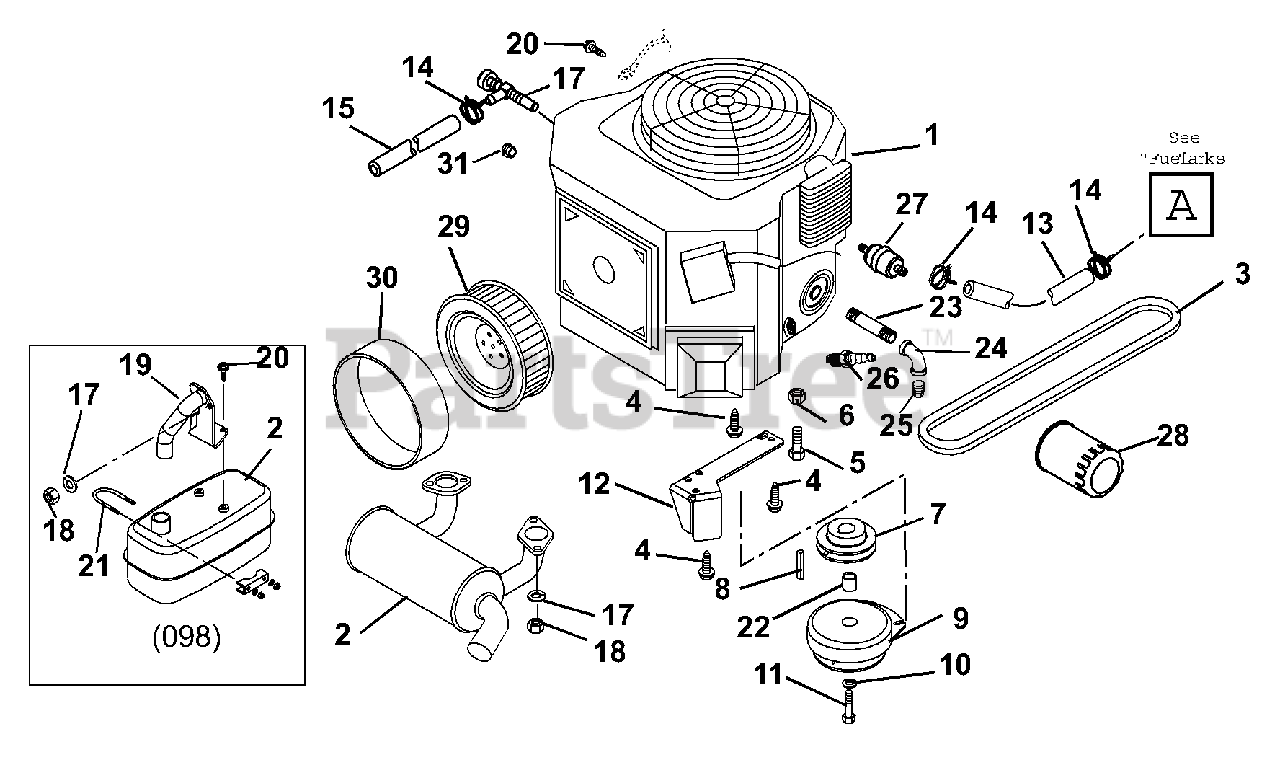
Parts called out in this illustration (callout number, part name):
1	18HP KOHLER COURAGE
2	MUFFLER, KOHLER
3	V-BELT, HA-RAW EDGE
4	@SCR-TAP .38-16X1.00 HWH TR YZ
5	@BLT-HEX .31-18X1.50 GR5 YWZC
6	@NUT-LK-NYL-FLG .31-18 YWZC
7	PLY-V 4.OO X 1.00
8	KEY-SQ .25X.625X.25 SAE 8630
9	CLUTCH, ELEC 1.000 ID 5219-55
10	@WSHR-LK .44X.109 REG YWZC
11	BLT-HEX .44-20X3.00 GR5 YWZC
12	STOP, CLUTCH
13	GAS LINE-BULK 1/4" I.D.
14	CLAMP-HOSE WIRE .490/.510X.116
15	GAS LINE-BULK 1/4" I.D.
16	COCK, OIL DRAIN
17	@WSHR-LK .31X.078 REG YWZC
18	NUT-HEX M8-1.25 YWZC
19	WMT, MANIFOLD
20	@SCR-TAP .25-20X.50 HWH TR YWZ
21	MUFFLER CLAMP
22	SPACER 1.005X1.5075X.375
23	NIPPLE, .38 X 2.50 LG BLK PIPE
24	ELBOW .375-18 NPTF
25	PIPE PLUG
26	SPARK PLUG
27	FILTER, FUEL
28	FILTER, OIL - KOH CV20
29	AIR FILTER
30	ELEMENT, PRE-CLEANER
